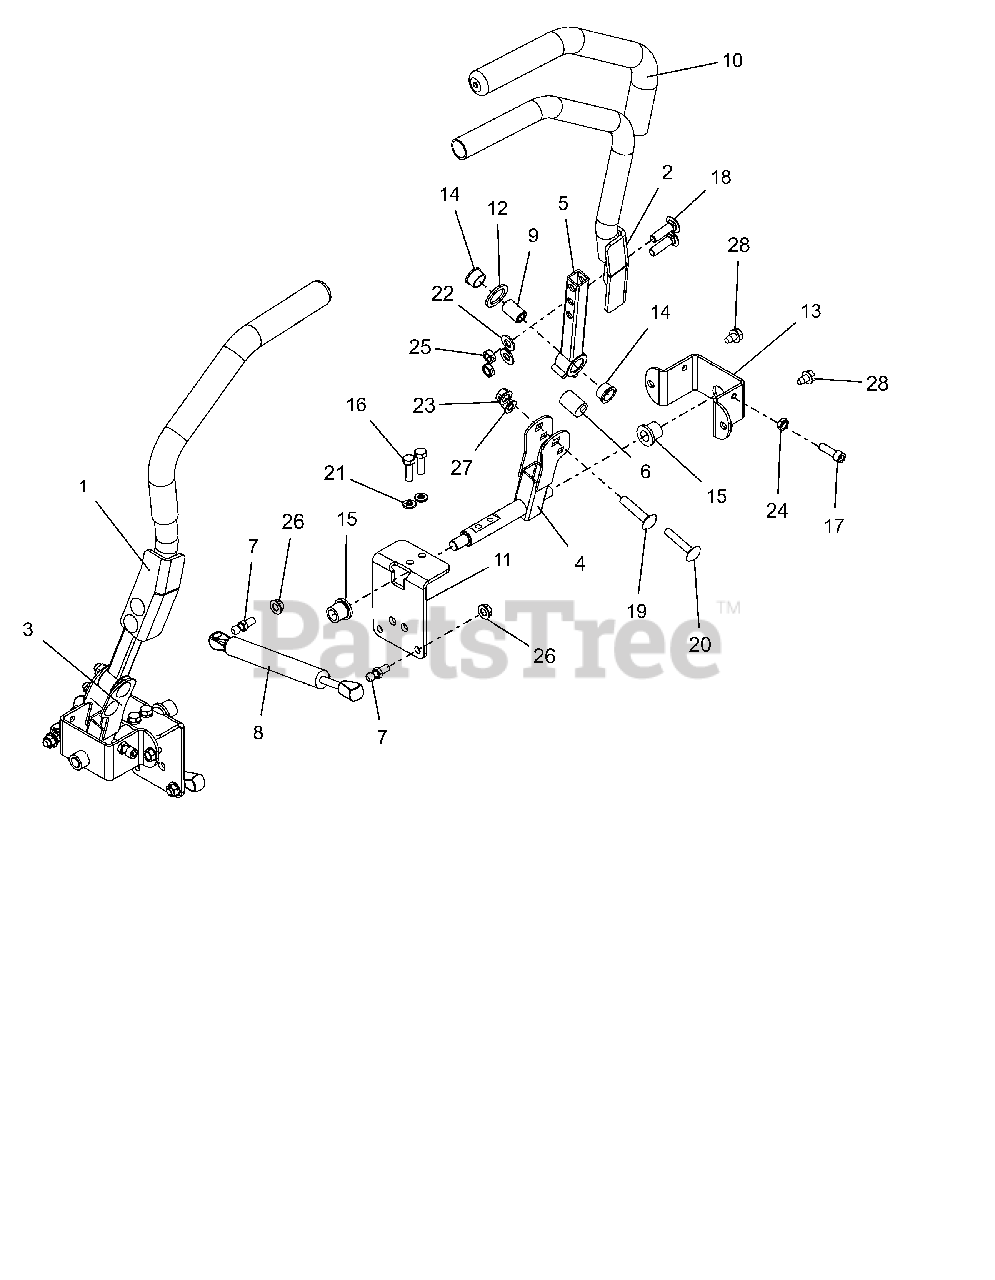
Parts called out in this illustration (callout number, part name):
1	WLDMT, STEERING HANDLE RH
2	WLDMT, STEERING HANDLE LH
3	WLDMT,STEERING ARM LOWER RIGHT
4	WLDMT,STEERING ARM LOWER LEFT
5	WLDMT, UPPER CONTROL ARM
6	BSHG,ECCEN .328X.750X1.01 PM
7	STUD- BALL
8	DAMPER, STABILUS
9	SPACER, .375X.625X.970 (PM)
10	GRIP, HANDLEBAR 15" FOAM
11	BRKT, STEEERING
12	WASHER, FRICTION .875X1.25X.10
13	BRKT, STEERING
14	BSHG-FLG, .625X.75X.450X.875
15	BSHG-FLG .515X.750X.745X1.00NY
16	BLT-HEX .31-18X1.00 GR8 YWZC
17	SCR, SKH .312-18X1.00 G8 ZC120
18	BLT,RHSSN-.375X1.25 G5 RIE5230
19	BLT,RHSSN-.375X1.75 G5 RIE5230
20	BLT,RHSSN-.312X1.75 G5 RIE5230
21	@WSHR-LK .31X.078 REG YWZC
22	@WSHR-FL-STL.406X.812X.065 YWZ
23	NUT-LK-CTR-FLG .38-16 YWZC
24	NUT- JAM .312-18 YWZC
25	@NUT-LK-CTR-JAM .375-16 YWZC
26	@NUT-LK-TOP-FLG .31-18 YWZC
27	@NUT-LK-NYL-FLG .31-18 YWZC
28	@SCR-TAP .31-18X.50 HWH TR YWZ
